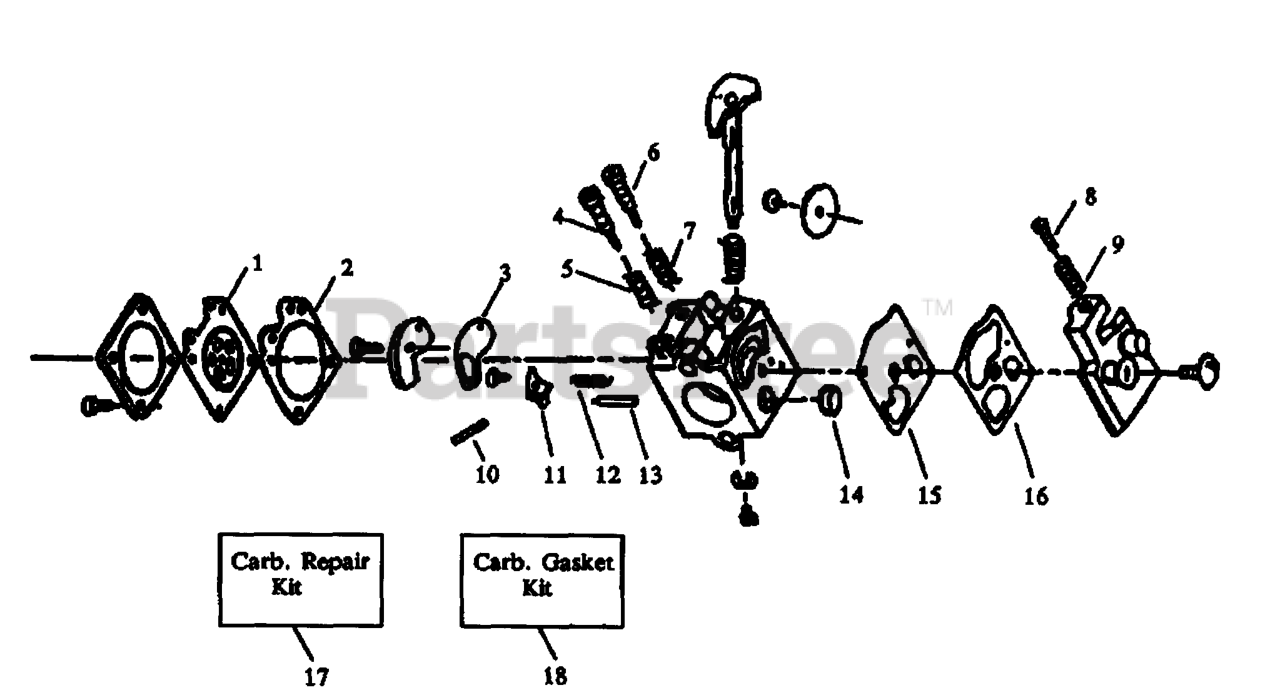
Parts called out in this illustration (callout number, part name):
1	DIAPHRAGM
2	GASKET-METER DIAP
3	GASKET-CIRCUIT PLATE
4	HI-SPEED NEEDLE
5	Hi Speed Needle Spring
6	NEEDLE - IDLE
7	SPRING-NEEDLE FUEL MIX
8	SCREW-IDLE SPEED
9	SPRING-IDLE SPEED
10	PIN
11	LEVER
12	Metering Lever Spring
13	INLET NEEDLEVALVE
14	SCREEN-DUTCH TWILL INLE
15	DIAP FUEL PUMP
16	GASKET-FUEL PUMP
17	REPAIR KIT
18	KIT-KWIK REPAIR
